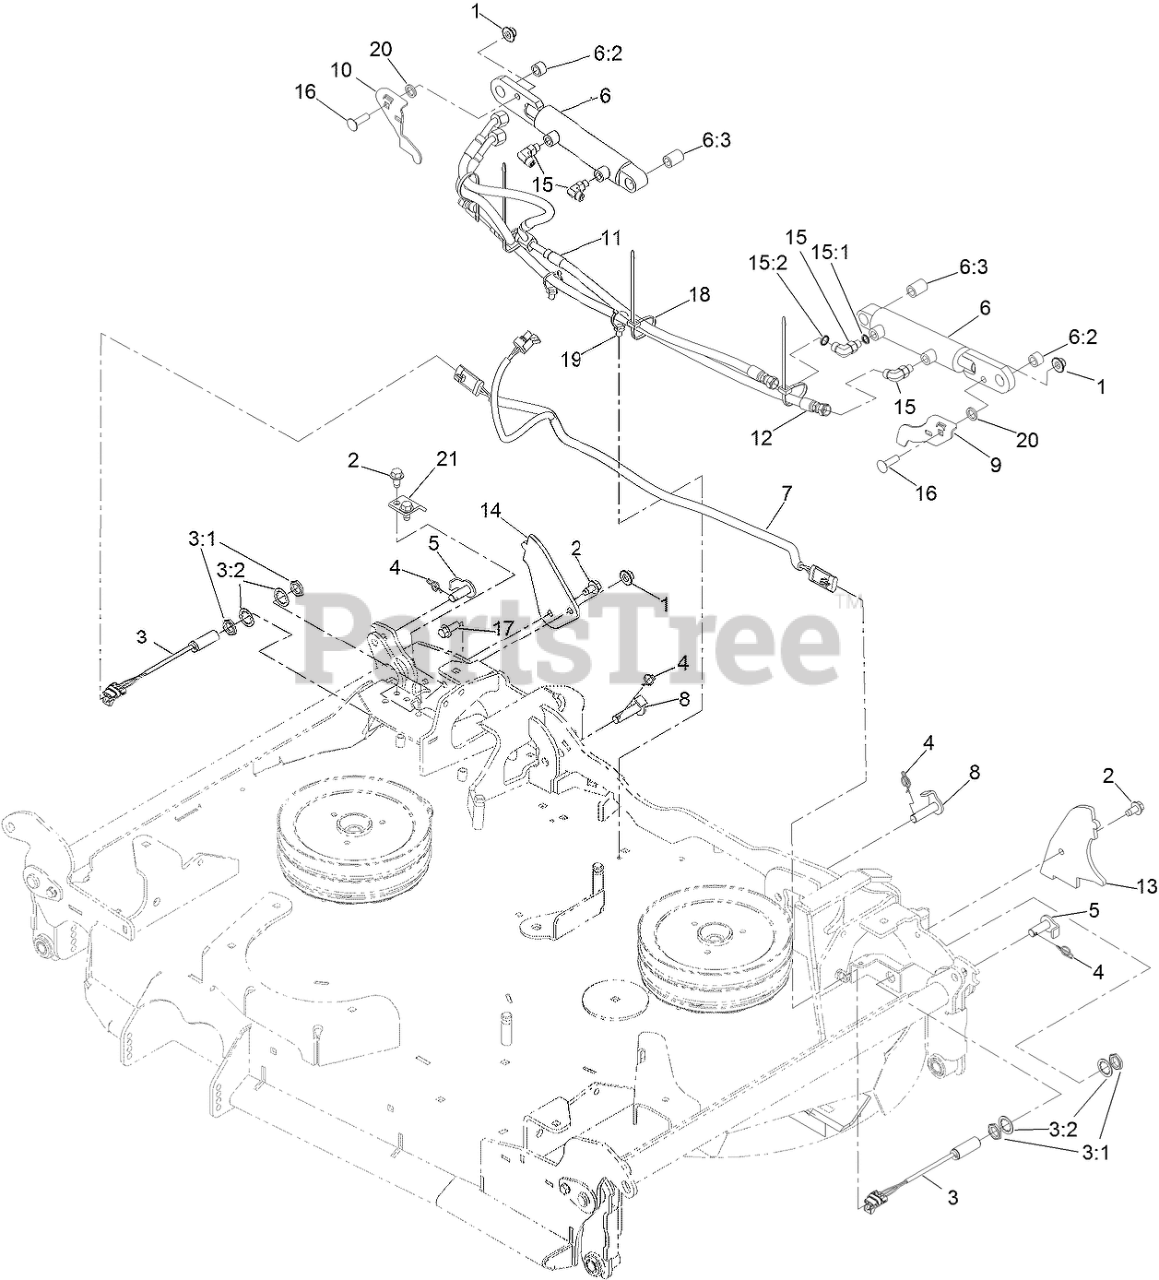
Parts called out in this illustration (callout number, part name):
1	Nut-Nyloc 3/8-16 Flg
2	SCREW-HWH
3	PROXIMITY SWITCH ASM
3:1	NUT-HEX
3:2	WASHER-LOCK, INTERNAL TOO
4	PIN-COTTER, LOCKING
5	EYE-PIN, CYLINDER
6	DECK FOLD CYLINDER ASM
6:2	BUSHING
6:3	BUSHING
7	HARNESS-WIRE
8	Pin-Cylinder
9	Plate-Proximity, LH
10	Plate-Proximity, RH
11	HOSE ASM
12	HOSE ASM
13	BRACKET-DECK STOP, LH
14	BRACKET-DECK STOP, RH
15	FITTING-ELBOW, 90 DEG
15:1	O-RING
15:2	O-RING
16	Bolt-Carriage 3/8-16 X 1 1/4
17	SCREW-HHF 3/8-16 X 1
18	TIE-CABLE
19	CLIP-TIE
21	BRACKET-GUARD, SWITCH (RH)
